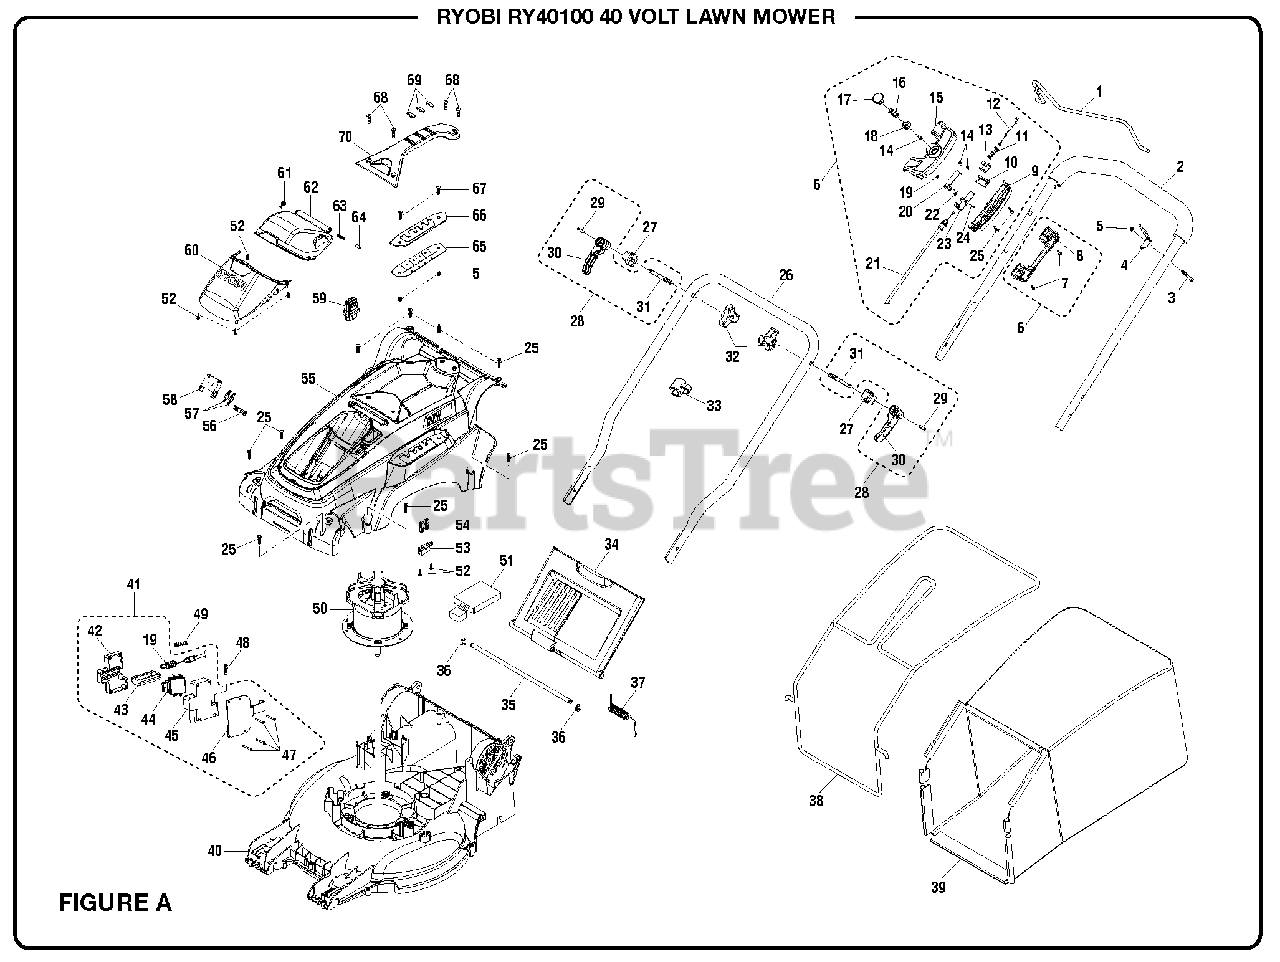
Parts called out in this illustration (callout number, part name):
1	Bail Handle (Power Lever)
2	Upper Handle Assembly
3	Bolt (M5 x 30 mm, Pan Hd.)
4	Stop Block
5	Lock Nut (M5)
6	Motor/Blade Control Assembly
7	Screw (M4.2 x 20 mm, Pan Hd.)
8	Lower Cover (Upper Handle)
9	Lower Cover (Starter Cables)
11	Compression Spring
12	Starter Cable( (Short)
13	Slide (Short Cable)
14	Screw (M3 x 8 mm, Pan Hd.)
15	Upper Cover (Control Assembly)
16	Button Return Spring
17	Start Button
18	Lower Button
19	Hex Nut (M3)
20	Spring Plate
21	Starter Cable (Long)
22	Torsion Spring
23	Slide (Long Cable)
24	Screw (M3 x 20 mm, Pan Hd.)
25	Screw (M3.5 x 20 mm, Pan Hd.)
26	Lower Handle
27	Pressure Block
28	Handle Lock Assembly
29	Spring Pin (5 x 26 mm)
30	Lock Handle
31	Bolt (M8 x 70 mm)
33	Cable Retainer
34	Rear Discharge Door
35	Rear Door Axle
36	Retaining Ring (E)
37	Torsion Spring (Rear Door)
38	Bag Frame
41	Switch Box Assembly
42	Switch Upper Cover
43	Switch Actuator
45	Switch Lower Cover
46	Mounting Bracket
47	Screw (M4.2 x 35 mm, Pan Hd.)
48	Screw (M4.2 x 45 mm, Pan Hd.)
49	Return Spring
51	Soft Start Circuit Board
52	Screw (M2.9 x 10 mm)
53	Key Holder
54	Key Receptacle
55	Deck Cover
56	Press Cover (Battery Connect)
57	Plate (Battery Connect)
58	Base (Battery Connect)
60	Battery Cover
61	Torsion Spring (Battery Door)
62	Battery Door
63	Pressure Spring
64	Battery Door Axle
65	Dust Gasket
66	Height Adjustment Plate
67	Screw (M5 x 16 mm, Pan Hd.)
68	Screw (M5 x 20 mm, Pan Hd.)
69	Handle Overlay
70	Carrying Handle
